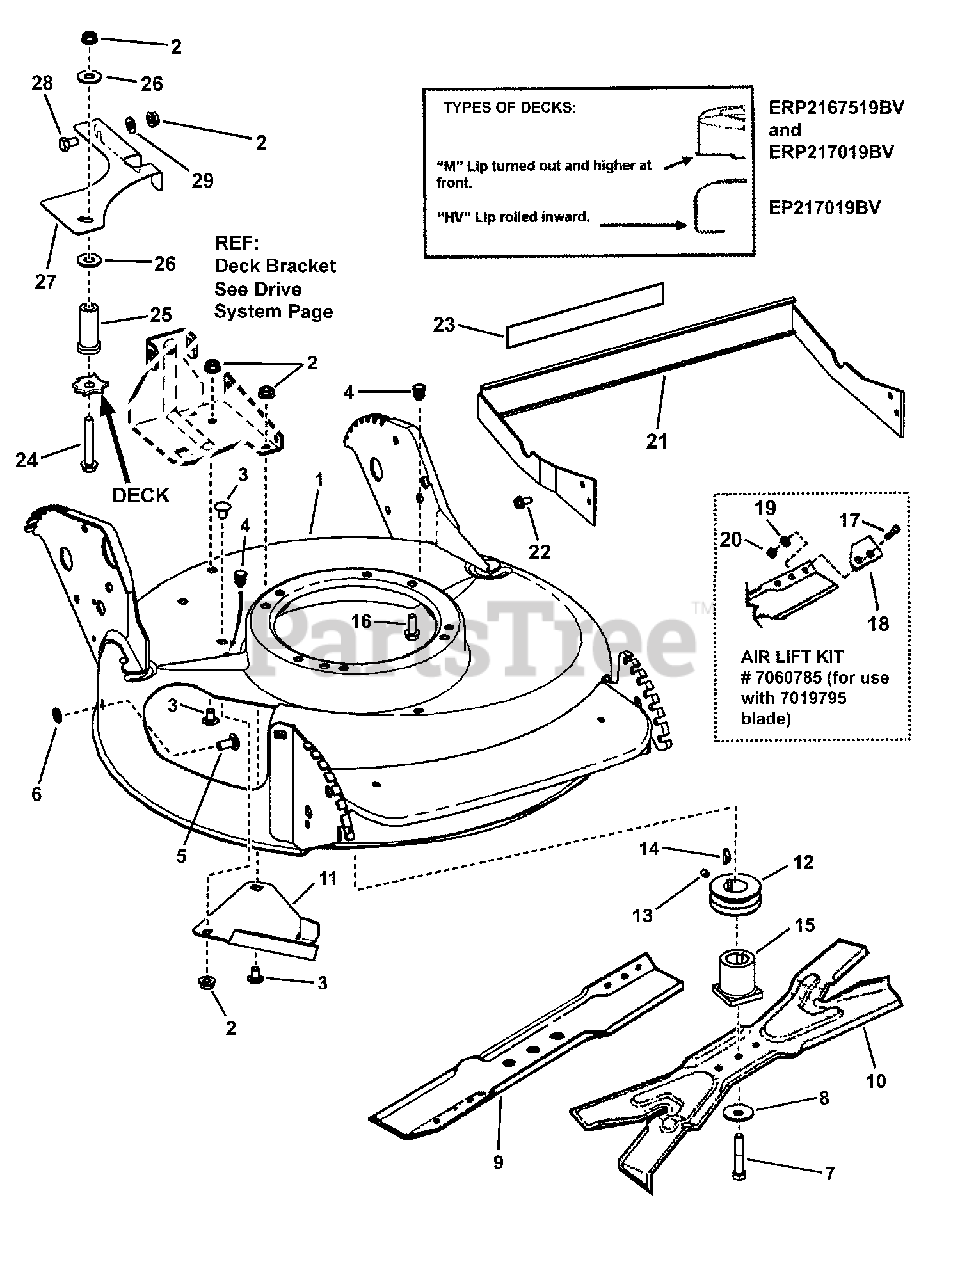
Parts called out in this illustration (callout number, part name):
1	WELDMENT, Deck, 21" Non-Adjust Air
1	WELDMENT, Deck, 21", S.P., HV, Core Model
2	NUT, 5/16-18 Hex Flange Lock, GR 5
3	BOLT, 5/16-18 x 1/2", Short Neck Carriage, GR 5
4	PLUG, Hole, Polyethylene
5	BOLT, 5/16-18 x 3/4" Short Neck Carriage GR 5
6	RETAINER, 5/16" Bolt
7	SCREW, 3/8-24 x 2" Hex Head Cap, GR 5
8	WASHER, Cone
9	BLADE, 21" Air Lift
10	BLADE, 21" Ninja (Quad Edge)
11	COVER, Belt
12	PULLEY, Engine (25mm I. D. x 2-1/8" O.D.)
13	SCREW, 5/16-18 x 1/2" Hex Socket Head
14	KEY, Woodruff #HP-506 Hi-Pro
15	HUB, Blade Drive 25mm I.D.
16	SCREW, 3/8-16 x 1" Self-Tapping
17	SCREW, 5/16-24 x 21/32" Oval Head Machine
18	AIR LIFT
19	WASHER, 5/16" Internal Tooth Lock
20	NUT, 5/16-24 Hex, GR 5
21	FENDER (Weldment), EP21S
22	SCREW, 1/4-20 x 1/2" Hex Flange Self-Tap
23	DECAL, Caution Symbols (International)
24	BOLT, 5/16-18 x 2-1/4" Hex Flange Lock
25	BUSHING, .388 x .625 x 1.62 Flanged
26	WASHER, 7/16" Flat
27	COVER, Belt- IP21S
28	SCREW, 5/16-18 x 1/2" Hex Head Cap, GR 5
29	WASHER, 5/16" Flat
